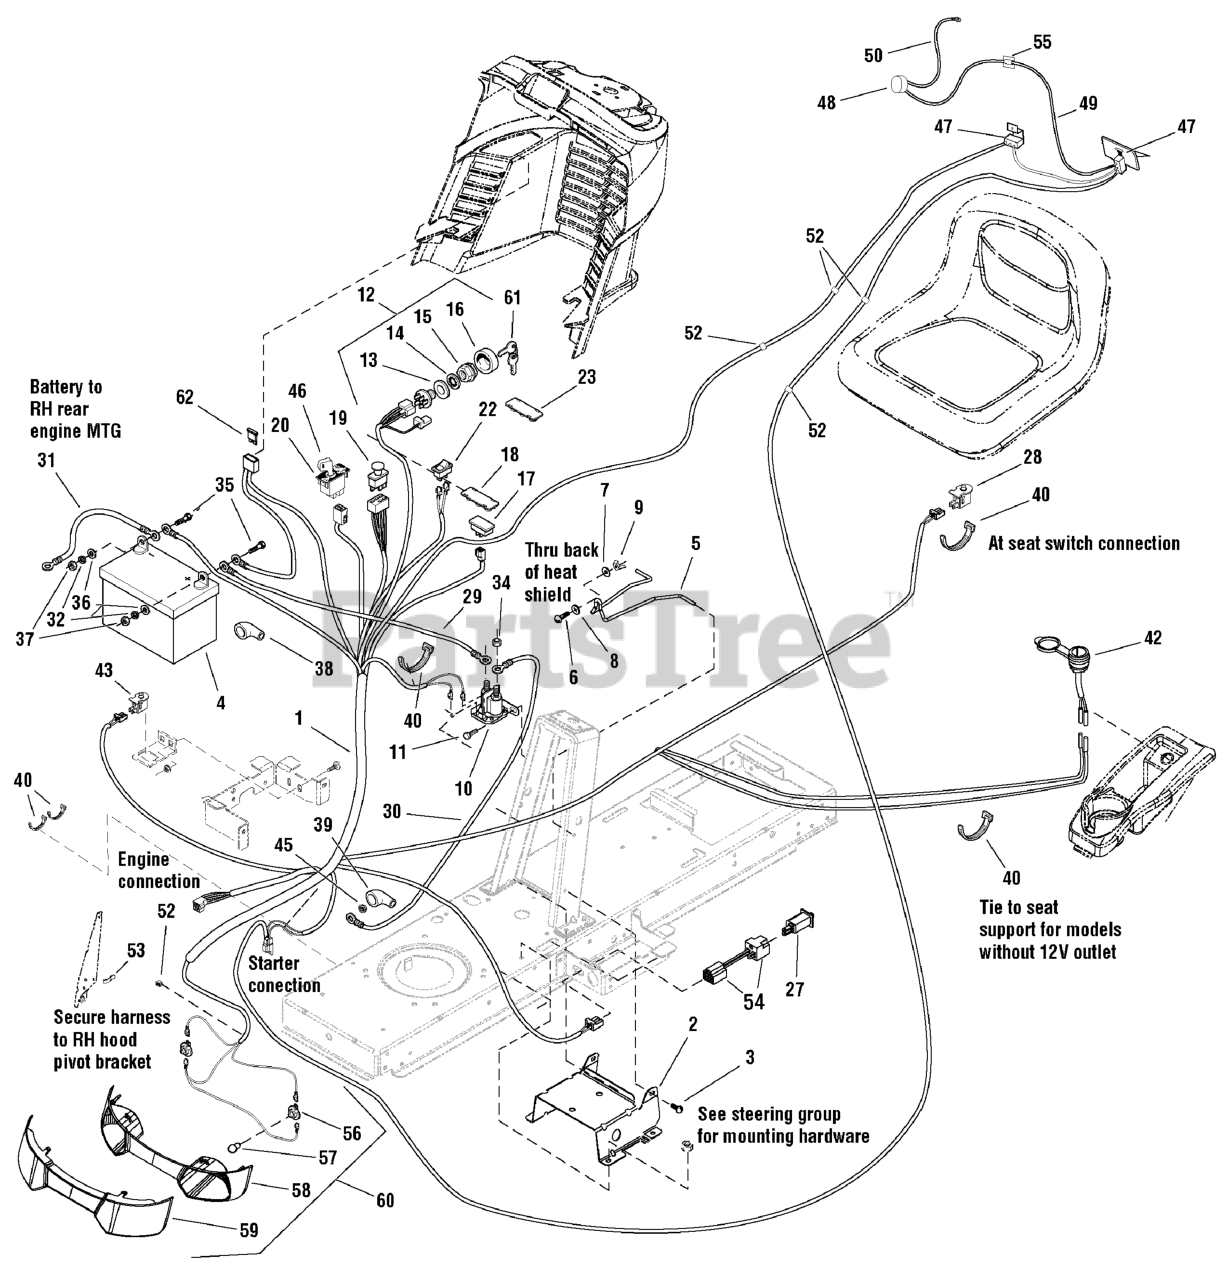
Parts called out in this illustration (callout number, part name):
1	Harness, Main
2	Support, Battery
3	Screw, Hex Washer Head, TAPTITE .31-18 x .62
4	Battery, 12V 230 AMP CCA DRY
5	Hold Down, Battery
6	Bolt, Round Head Carriage .25-20 x .88
7	Washer, Flat .25
8	Nut, Push .25
9	Nut .25 ESNA
10	Solenoid, 12V
11	Screw, Hex-Washer Head TAPTITE .25-20 x .50
12	Switch Assembly, Ignition
13	Washer .62
14	Lock Washer, Int. Tooth .62
15	Nut, Hex-Flange, Ignition Switch .62 - .32
16	Cover, Ignition Switch
17	Hour Meter
18	Plug, Hour Meter
19	SWITCH, PTO, Push/Pull
20	SWITCH, RMO Module Only
22	SWITCH, Head lights
27	SWITCH, Push (Foot Pedal)
28	SWITCH, Push NC (Seat)
29	CABLE #6 10.0 Lg Red
30	CABLE, #6 25.0 Lg Red
31	CABLE, #6 20.0 Lg Black
32	LOCKWASHER, Spring, 1/4
34	NUT, Hex KEPS, 5/16-24
35	CAPSCREW, Hex 1/4-20 x 3/4
36	WASHER, Flat 1/4
37	NUT, Hex, 1/4-20
38	BOOT, Insulator, Battery
39	BOOT, Insulator, Red
40	TIE, RT 360 /L=150/
42	PLUG, Aux, 12V, (With Cover)
43	SWITCH, NO (RMO)
45	NUT, Flange, Whiz 1/4-20
46	KEY, RMO Module Plastic
47	MICROSWITCH, MKH 12 D13 S1
48	BEEPER, PF 27 A 29 EP
49	WIRE, 9-8316-615
52	CABLE CLIP
53	CLIP, Speed Wire
54	PLUG, Shut-Off
55	CLIP, Cable WCK 460 01/A
56	SOCKET ASSEMBLY
57	BULB, 1141-12V 21CP
58	REFLECTOR, Headlight
59	LENS, Headlight
60	HEADLIGHT ASSEMBLY
61	KEY, Ignition (Set of 2)
